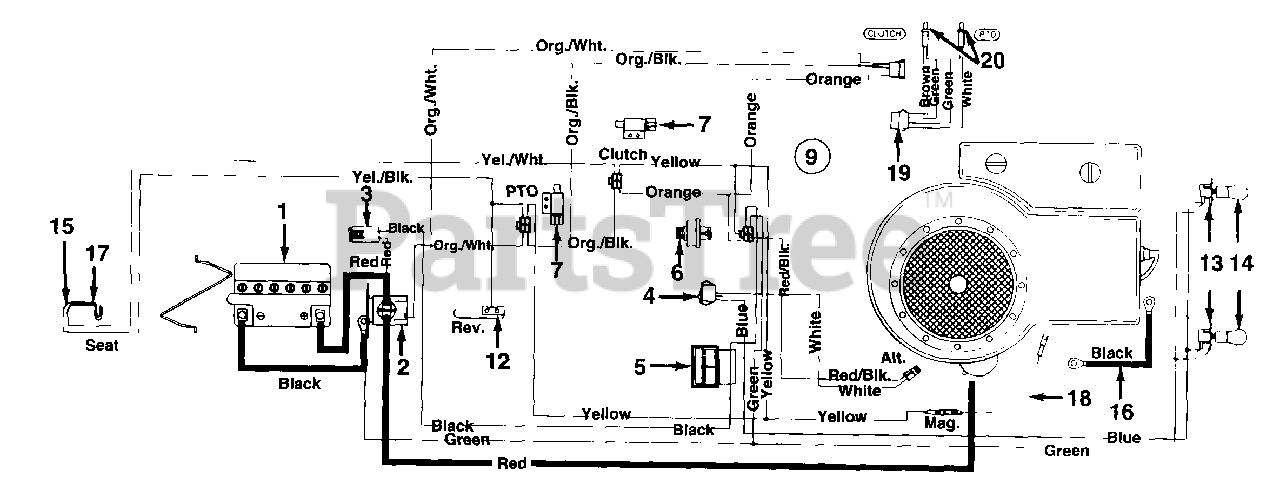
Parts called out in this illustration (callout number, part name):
1	Battery
2	Solenoid
3	Fuse 7.5 Amps
4	Light Switch
5	Ammeter
6	Ignition Switch
7	Safety Switch (Clutch)
9	Wire Harness w/o Ammeter
12	Safety Switch (Reverse)
13	Socket
14	Bulb (Headlight)
15	Safety Switch (Seat)
16	Ground Wire 7.5" Lg.
17	Safety Switch (Seat)
18	Harness Adaptor
19	Monitor Harness
20	Monitor Bulb
